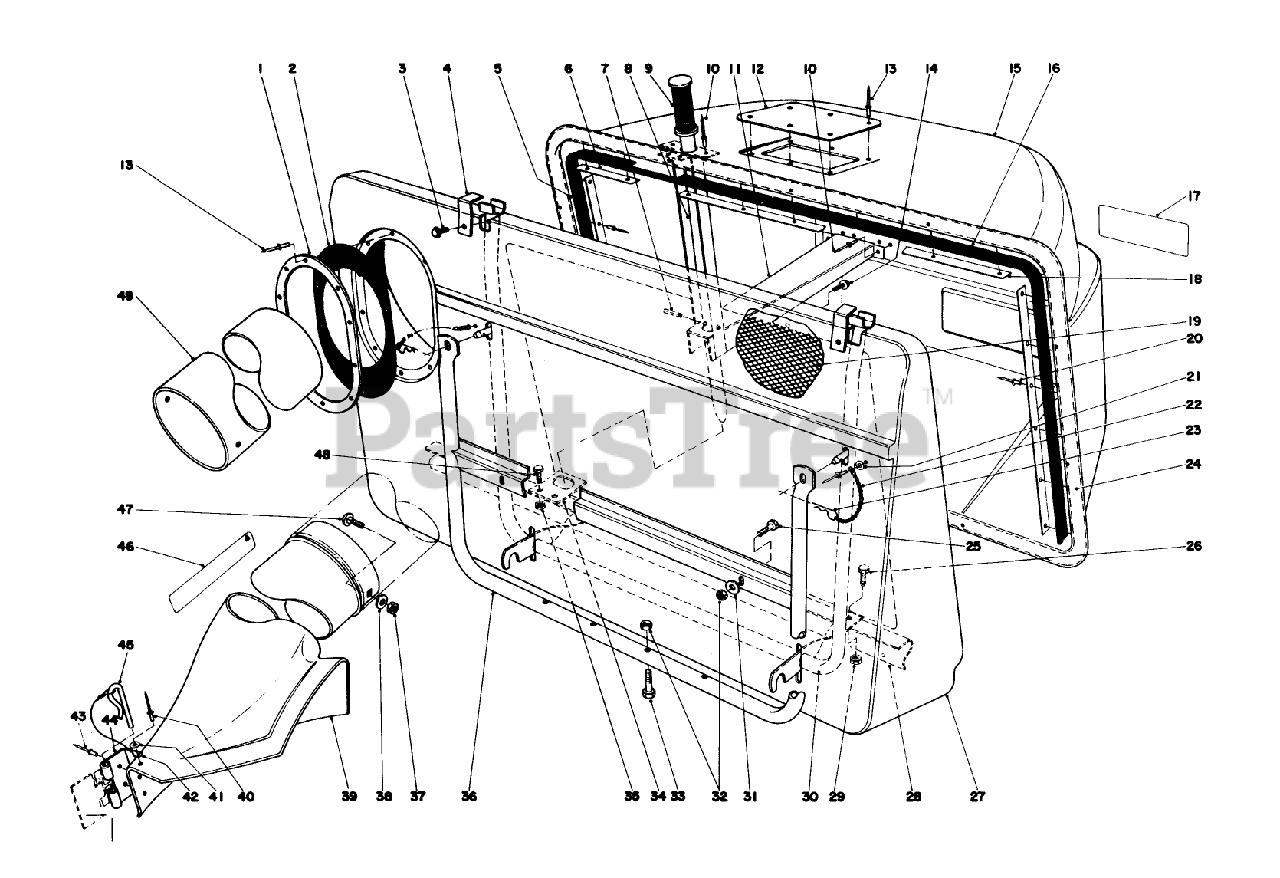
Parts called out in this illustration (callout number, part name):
1	RING-RETAINING
2	RING-RETAINER, RUBBER
3	SCREW-HWH
7	5/16 X 1-1/8 ROLL PIN
8	DUMP HANDLE ASM
14	SCREW-HWHTF
21	WASHER
23	PIN-HAIR
25	SCREW-HH
26	SCREW-HH
29	NUT-LOCK, CONE
31	WASHER-PLAIN
32	NUT-LOCK, CONE
33	SCREW-HH
36	BAG SUPPORT WA *
37	NUT-HEX, SIDE DEFORM
38	WASHER-FLAT
39	CHUTE ASM
40	RIVET-BLIND
41	WASHER-PLAIN
42	LANYARD
43	RIVET-BLIND
44	BRACKET-MOUNTING, CHUTE
45	PIN-LOCKING, CHUTE
48	SCREW-HH
